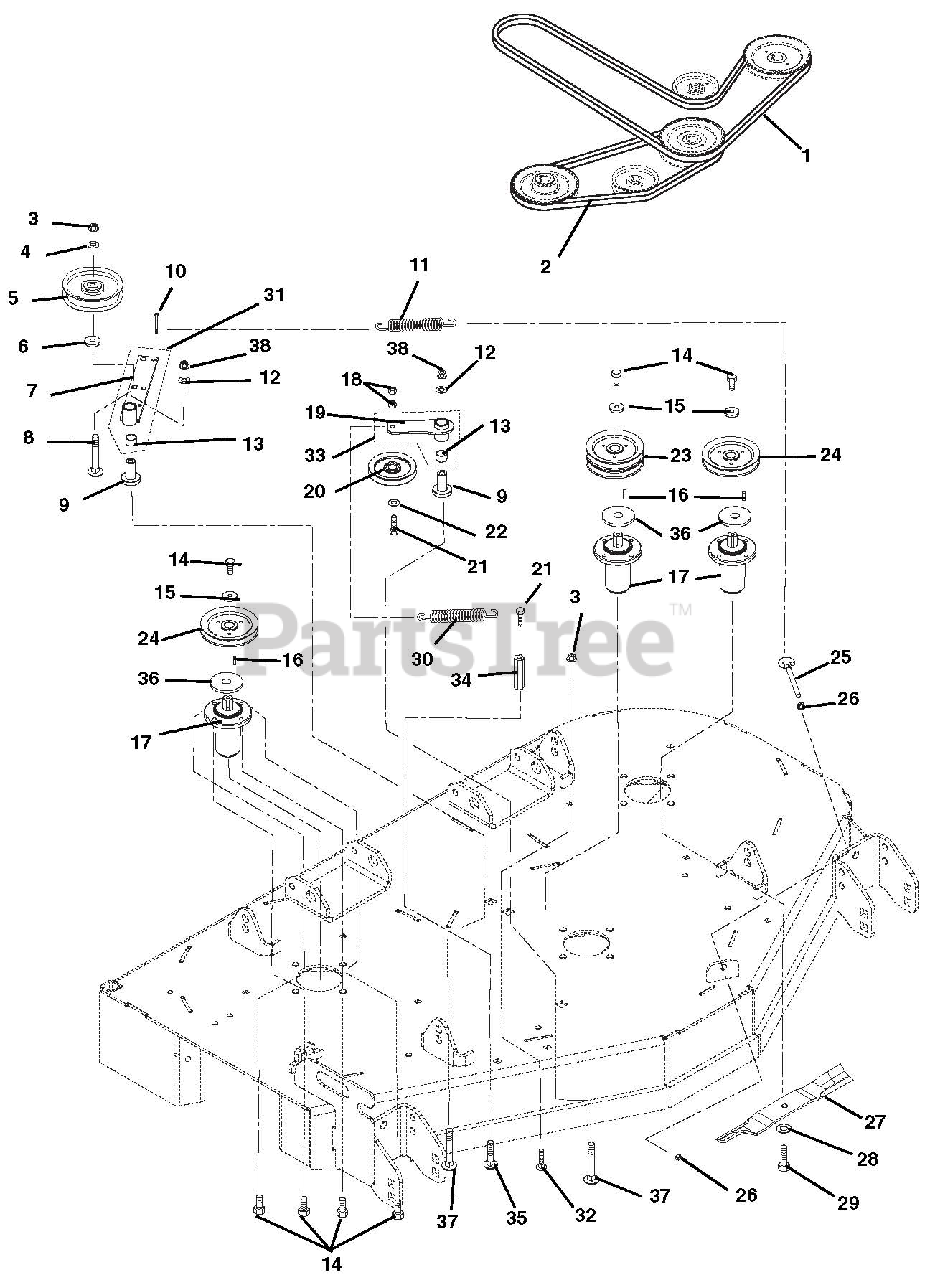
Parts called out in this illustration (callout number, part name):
1	Belt, HB 119.75" Long, Wrapped
2	V-Belt, 51.18" Long Cog B-Section
3	Nut, .38-16 Nyloc Flange
4	Washer, Flat Steel .375x 1.125 x .065
5	Idler, Flat, 3.8 x 4.00 x 1.06
6	Spacer, .380 x .750 x .236
7	PTO Idler Pivot Arm
8	Bolt, Round Head Square Neck .38-16 x 2.25 Grade 5
9	Bearing, Pedestal
10	Bolt, Shoulder EP .38-16 x .30 Hex
11	Spring, Extension (Deck Idler)
12	Washer, Flat Steel .531x 1.250 x.100
13	Bushing, 1.00 x 1.125 x 1.936
14	Bolt, Hex .38-16 x 1.00
15	Washer, Flat Steel .406 x 1.50 x .245
16	Key, Square .25 x .25 x 1 RC 40-50
17	Spindle Assembly
18	Nut, Locking-Center .38-16
19	Weldment, Idler Arm
20	Sheave, .38" ID x 5" OD
21	Bolt, Hex .38-16 x 2.25
22	Washer, Flat Steel .406 x .812 x .065
23	Sheave, Double 1" ID x 5.50" OD
24	Sheave, Single 1" ID x 5.50" OD
25	Bolt, .38-16 x 4.00 .62 Diameter Eye
26	Nut, Hex, Jam .375-16
27	Blade, Mower, 44 in. & 48 in. Decks
28	Washer, Bellville .63 x 1.625 x.14
29	Bolt, Hex .62-18 x 1.75 Grade 8
30	Spring, Extension
31	Assembly, PTO Idler Pivot Arm
32	Bolt, Round Head Square Neck .50-13 x 1.5, Full Thread, Grade 5
33	Assembly, Idler Pivot Arm
34	Nut, Coupling .375-16 x 1.75
35	Bolt, Round Head Square Neck .38-16 x 1.00
36	Retainer, Grease
37	Bolt, Round Head Square Neck .50-13 x 3.50
38	Nut .50-13 Nyloc Flange
